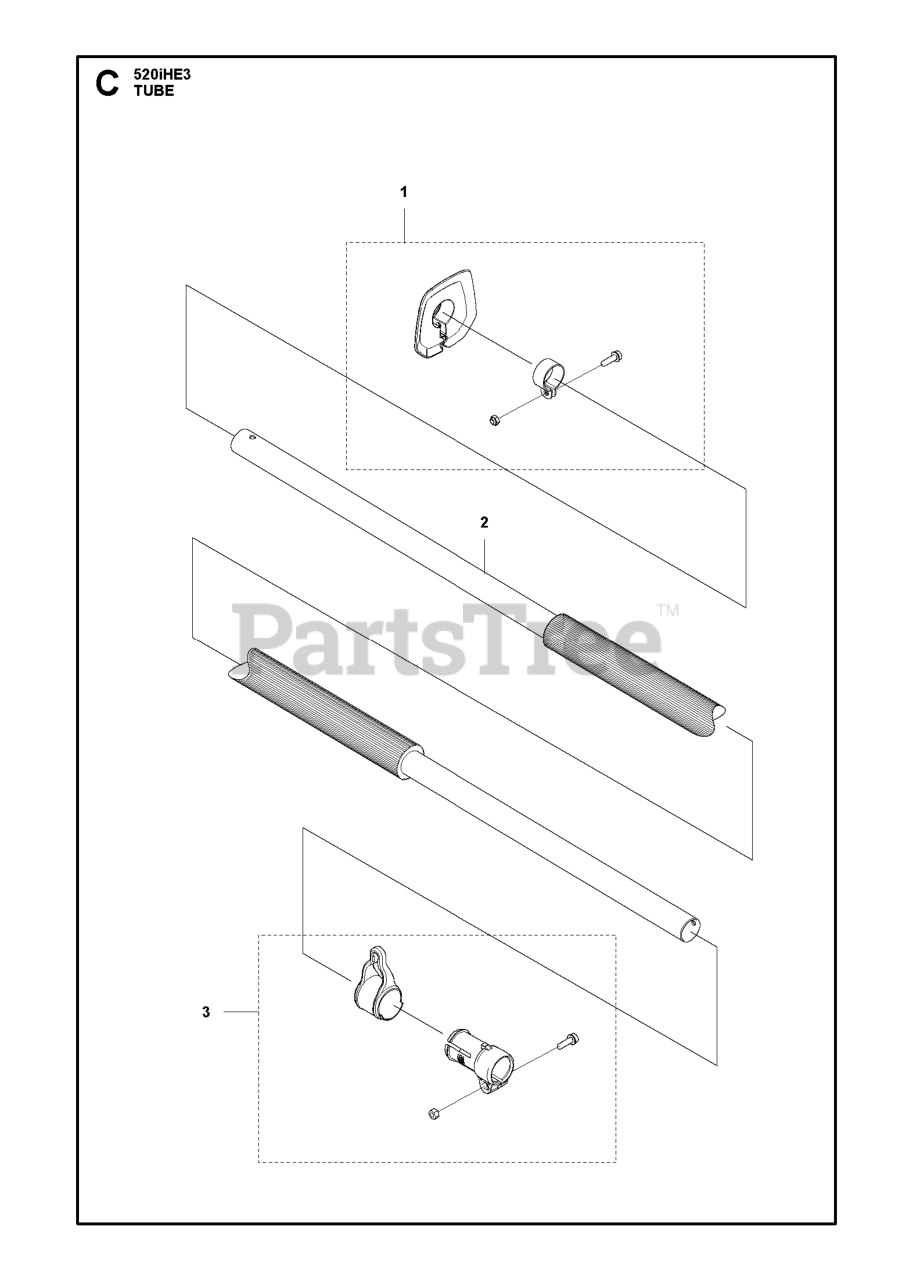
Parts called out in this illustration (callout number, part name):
1	HANDGUARD ASSY
2	TUBE ASSY POLE H
3	CORD BRACKET CPL
